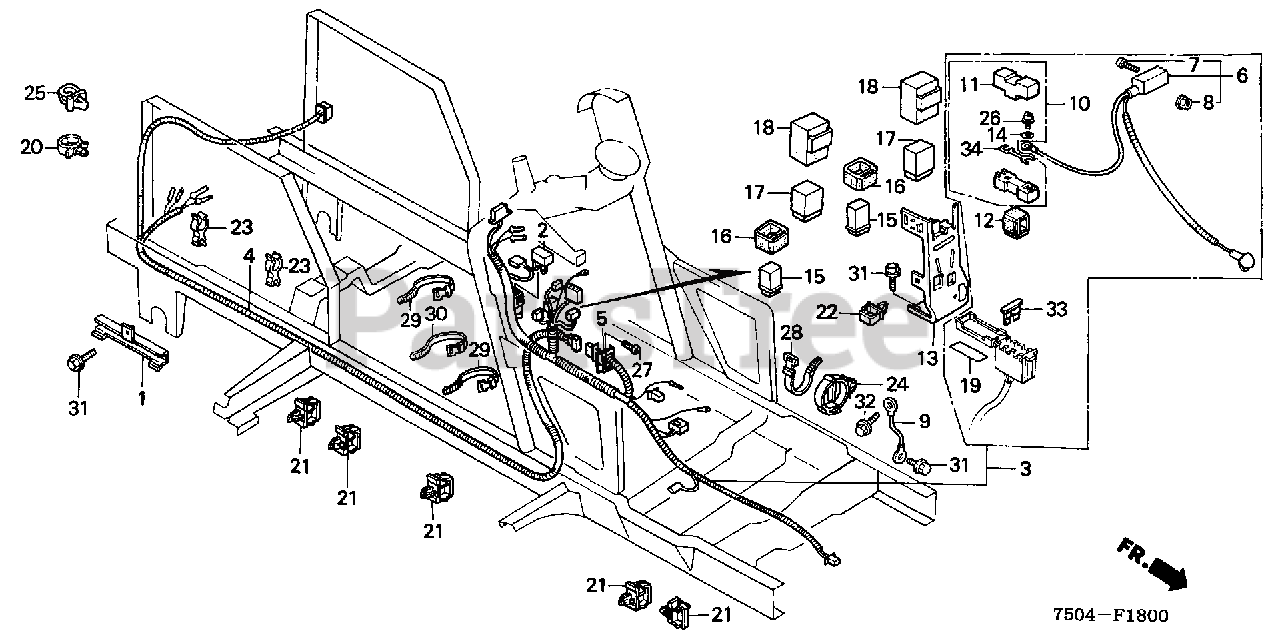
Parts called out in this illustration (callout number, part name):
1	PROTECTOR, WIRE
2	RECTIFIER ASSY., SILICON (STANLEY)
3	WIRE HARNESS ASSY., MAIN
4	SUB-WIRE HARNESS ASSY., RR.
5	HOLDER, CONNECTOR
6	CABLE ASSY., STARTER
7	BOLT, BATTERY TERMINAL (SUMITOMO)
7	BOLT, BATTERY TERMINAL
8	NUT, BATTERY TERMINAL (SUMITOMO)
9	CABLE ASSY., BONDING
10	BOX, MAIN FUSE (NOT AVAILABLE)
11	COVER (NOT AVAILABLE)
12	SUSPENSION, MAIN FUSE
13	BRACKET, ELECTRIC PARTS
14	WASHER, PLAIN (3X10)
15	RELAY, CONTROL
16	SUSPENSION, CONTROL RELAY
17	RELAY, STARTER
18	SUSPENSION, STARTER RELAY (OMRON)
18	SUSPENSION, STARTER RELAY (MITSUBA)
19	LABEL, FUSE
20	CLIP, WIRE HARNESS
21	CLIP, HARNESS (15MM) (BLUE)
22	CLIP, WIRE HARNESS (13MM) (GRAY)
23	CLAMP, PIPE (5-13)
24	STRAP, WIRE HARNESS (25MM) (BLACK)
25	CLIP, WIRE HARNESS
26	SCREW, PAN (3X8)
27	SCREW, PAN (6X8)
28	BAND B1, CABLE
29	BAND B2, CABLE HARNESS
30	BAND B3, CABLE HARNESS
31	BOLT, FLANGE (6X10)
32	BOLT, FLANGE (8X12)
33	FUSE, BLADE (5A)
34	FUSE F (20A)
